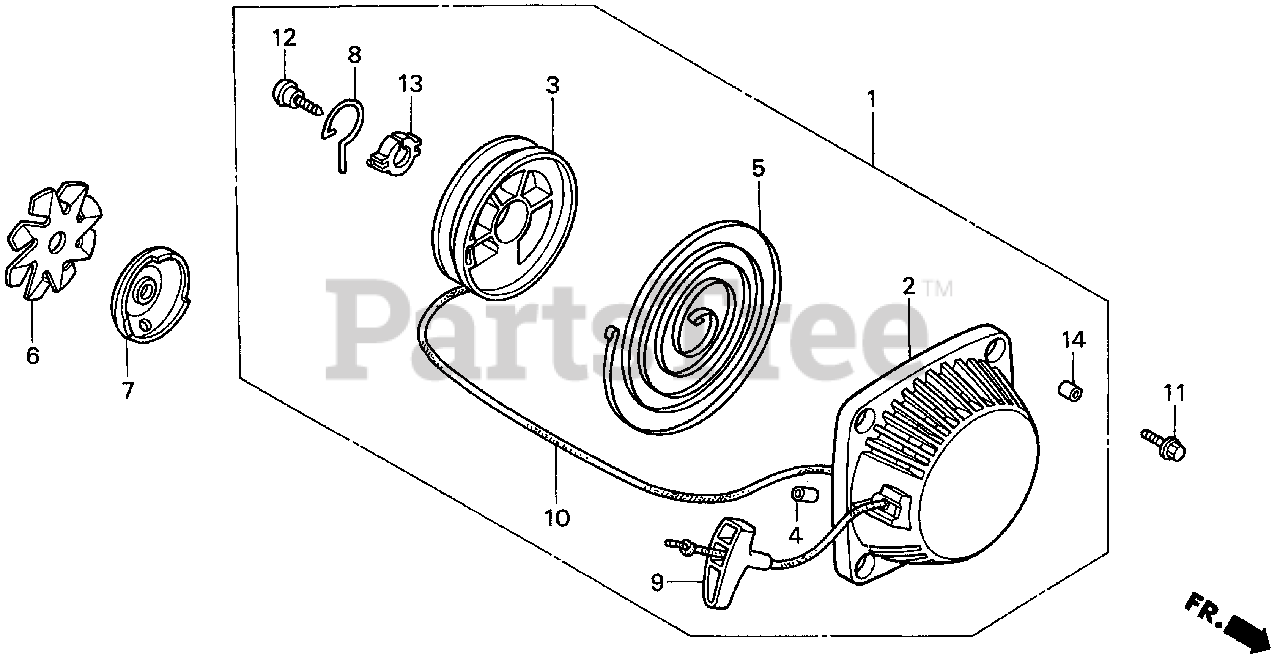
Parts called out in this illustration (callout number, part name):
1	STARTER ASSY., RECOIL *NH1* (BLACK)
2	CASE, RECOIL STARTER
3	REEL, RECOIL STARTER
4	GUIDE, ROPE
5	SPRING, RECOIL STARTER
6	FAN, RATCHET
7	PULLEY, RECOIL STARTER
8	SWINGARM
9	KNOB, RECOIL STARTER
10	ROPE, RECOIL STARTER
11	BOLT, FLANGE (5X18)
12	SCREW, SETTING
13	COLLAR
14	COLLAR
